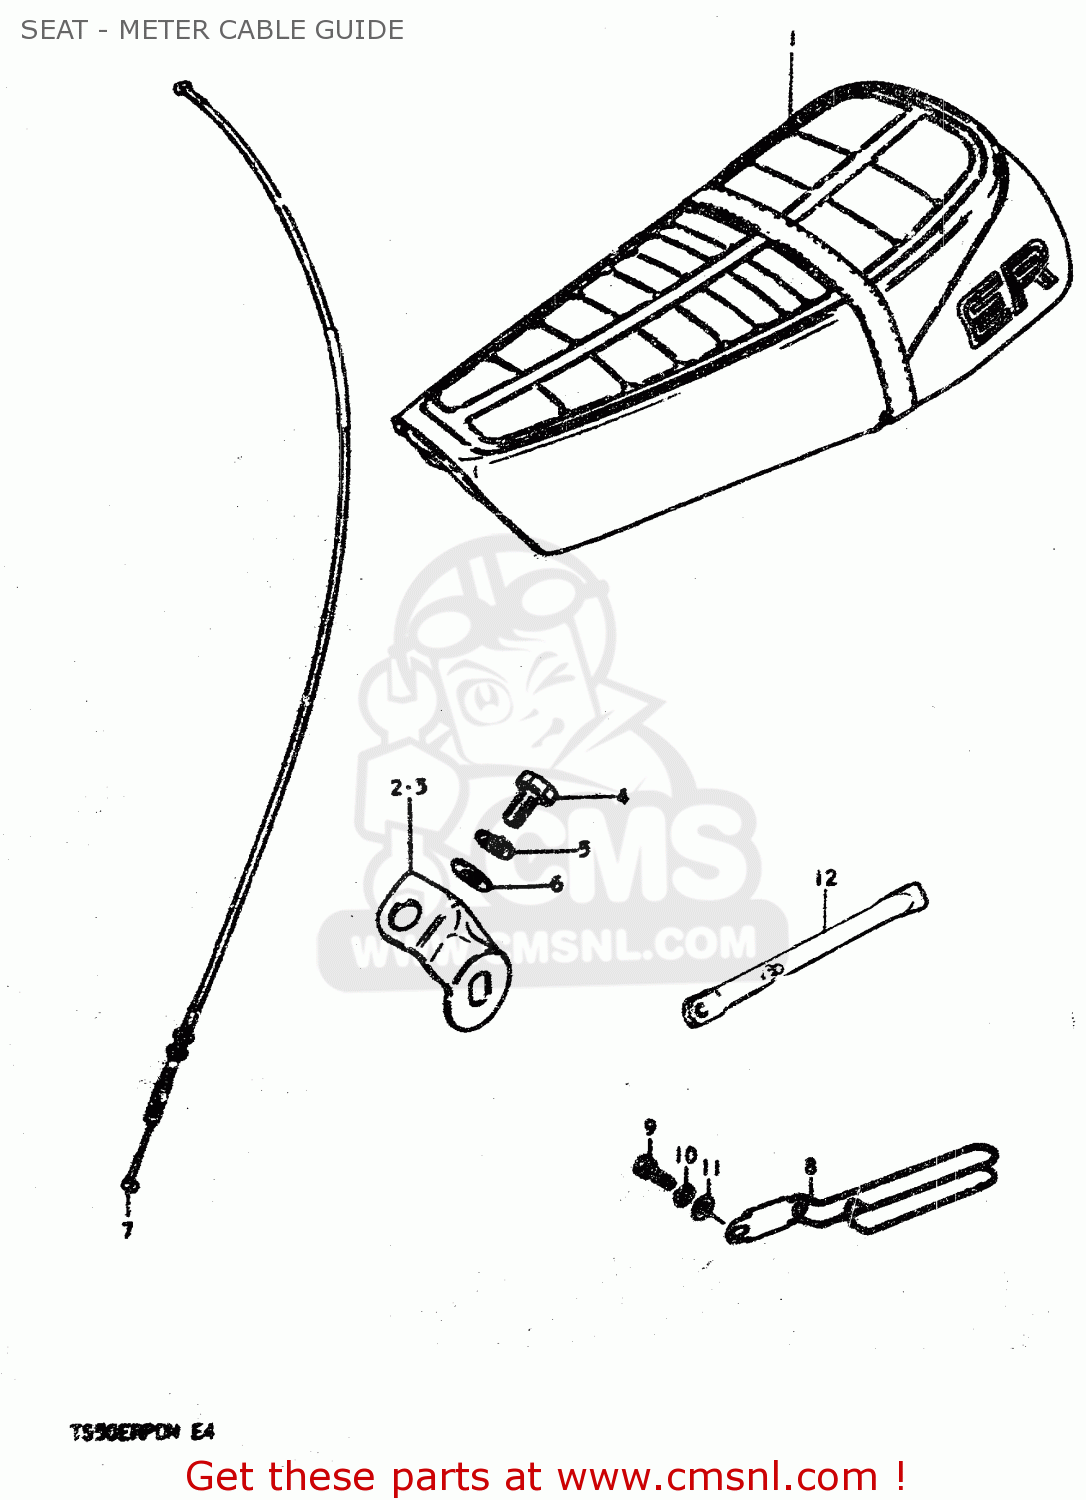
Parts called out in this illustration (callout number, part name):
1	SEAT ASSY (BLACK)
2	BRACKET,TURNSIGNAL LAMP,R
3	BRACKET,TURNSIGNAL LAMP,L
4	BOLT
5	LOCK WASHER
6	WASHER
7	CABLE ASSY, BRAKE
8	GUIDE,CABLE
9	BOLT 8X12
11	WASHER
12	STAND,SIDE
